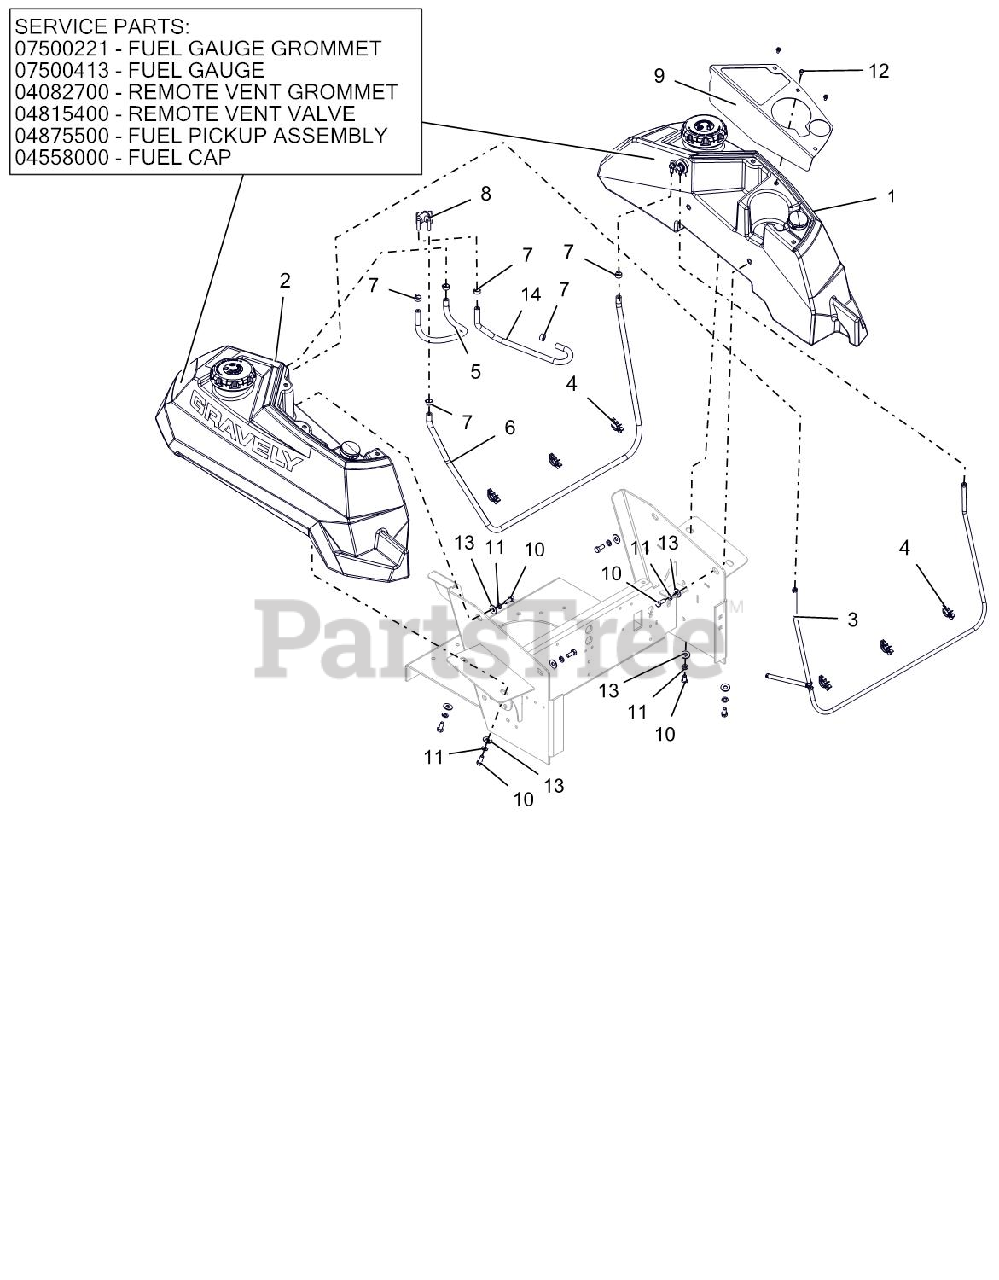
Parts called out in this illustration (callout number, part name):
1	ASM, LH - PT100 FUEL TANK
2	ASM, RH - PT100 FUEL TANK
3	ASM, VAPOR LINE
4	WIRE CLIP
5	HOSE, .25 LOW-PERM BULK GAS
6	HOSE, .25 LOW-PERM BULK GAS
7	CLAMP, FUEL LINE
8	VALVE, FUEL
9	PT100 CUPHOLDER PANEL - RED
10	@BLT-HEX .31-18X.75 GR5 YWZC
11	@WSHR-LK .31X.078 REG YWZC
12	SCR-MCH 10-24X.38 HWHSTAINLESS
13	@WSHR-FL-STL.38X.875X.083 YWZC
14	HOSE, .25 LOW-PERM BULK GAS
15	GROMMET, FUEL GAUGE
16	GAUGE, REMOTE SEALED FUEL
17	GROMMET, REMOTE VENT NITRILE
18	VALVE, 2-WAY
19	ASSM,LRG TANK FUEL PICKUP LINE
20	CAP, FUEL VENTIN AUTOLOCK
